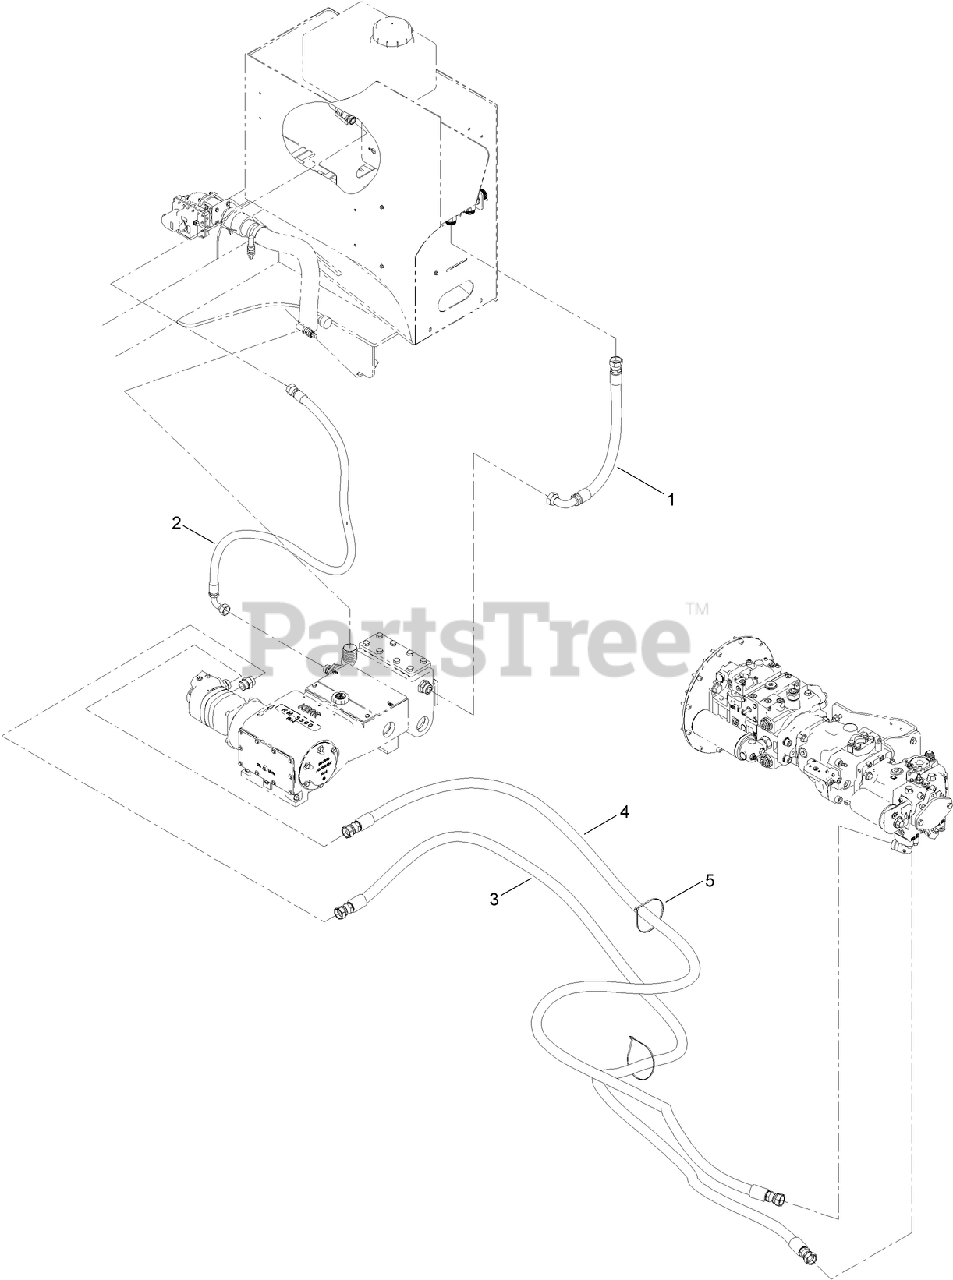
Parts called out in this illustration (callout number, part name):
1	HOSE ASM-HYD
2	HOSE ASM-HYD
3	HOSE ASM-HYD
4	HOSE ASM-HYD
5	TIE-CABLE
